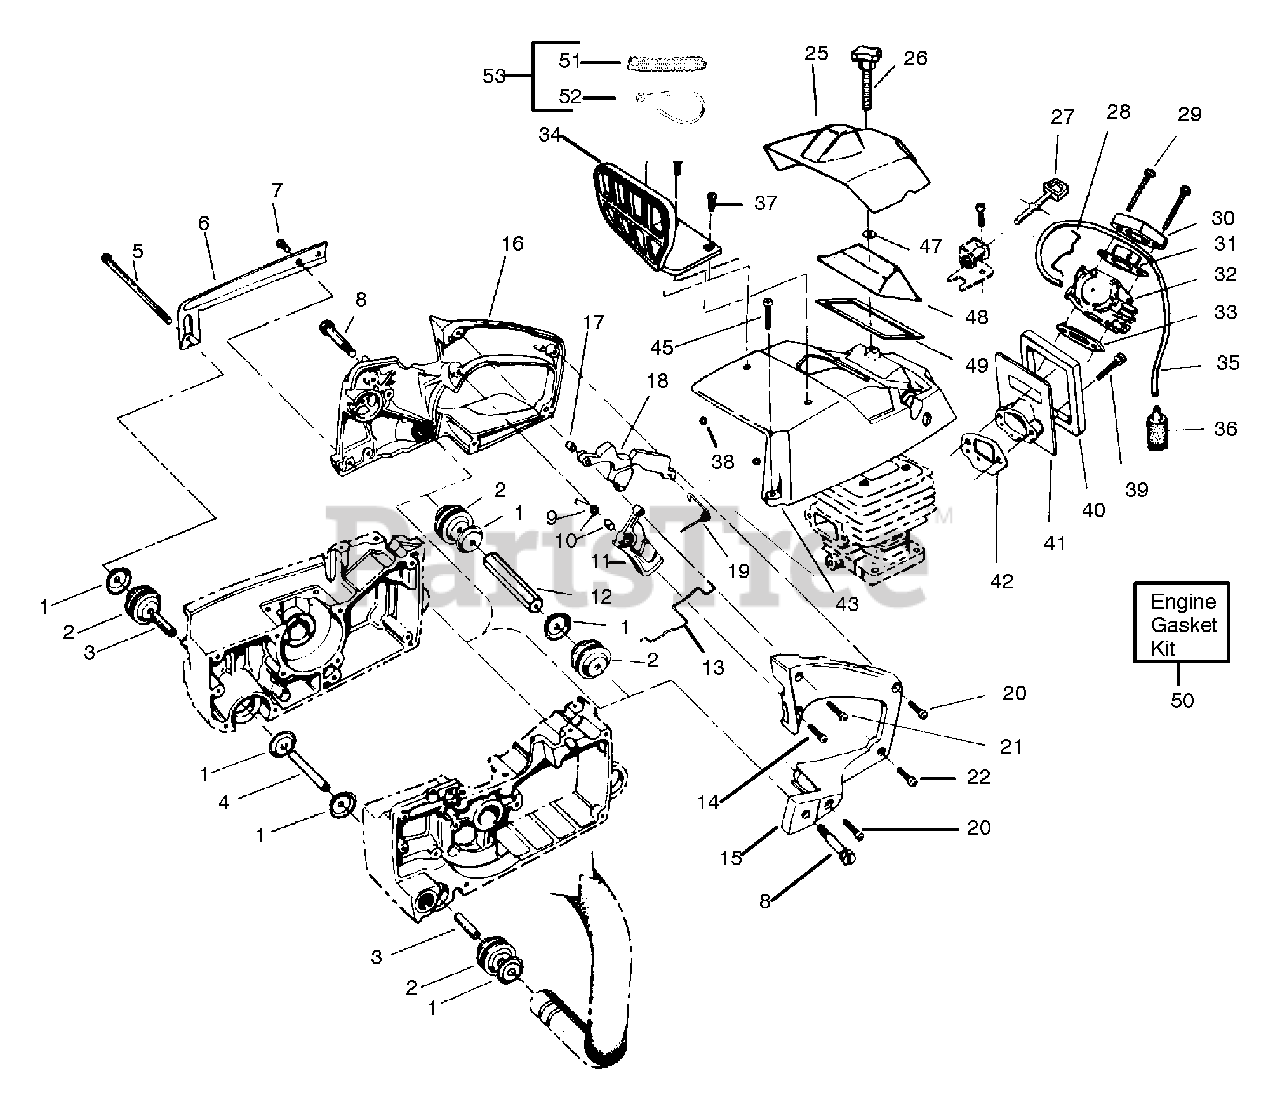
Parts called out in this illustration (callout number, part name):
1	Cup Isolator
2	Isolator Rear Handle
6	Handle Brace
8	Shoulder Screw
9	Trigger Spring
10	Trigger Bushing
11	Trigger Throttle
12	Isolator Spacer
13	Throttle Wire
14	Shoulder Screw
15	Rear Handle-Left
16	Rear Handle-Right
18	Throttle Lock
19	Throttle Lock Spring
25	Carburetor Cover
25	Winter Kit Carb. Cover
26	Carburetor Cover Knob
27	Choke Rod
28	Choke Wire
31	Carburetor Seal Bracket
32	Carburetor
34	Handguard
35	Line Kit
36	Fuel Pick-Up Ass'y
38	Nut
40	Adaptor Seal
41	Carburetor Adaptor
43	Cylinder Shield
47	Retainer
48	Air Filter
50	Engine Gasket Kit
51	Winter Screen
52	Tie Strap
53	Winter Kit
